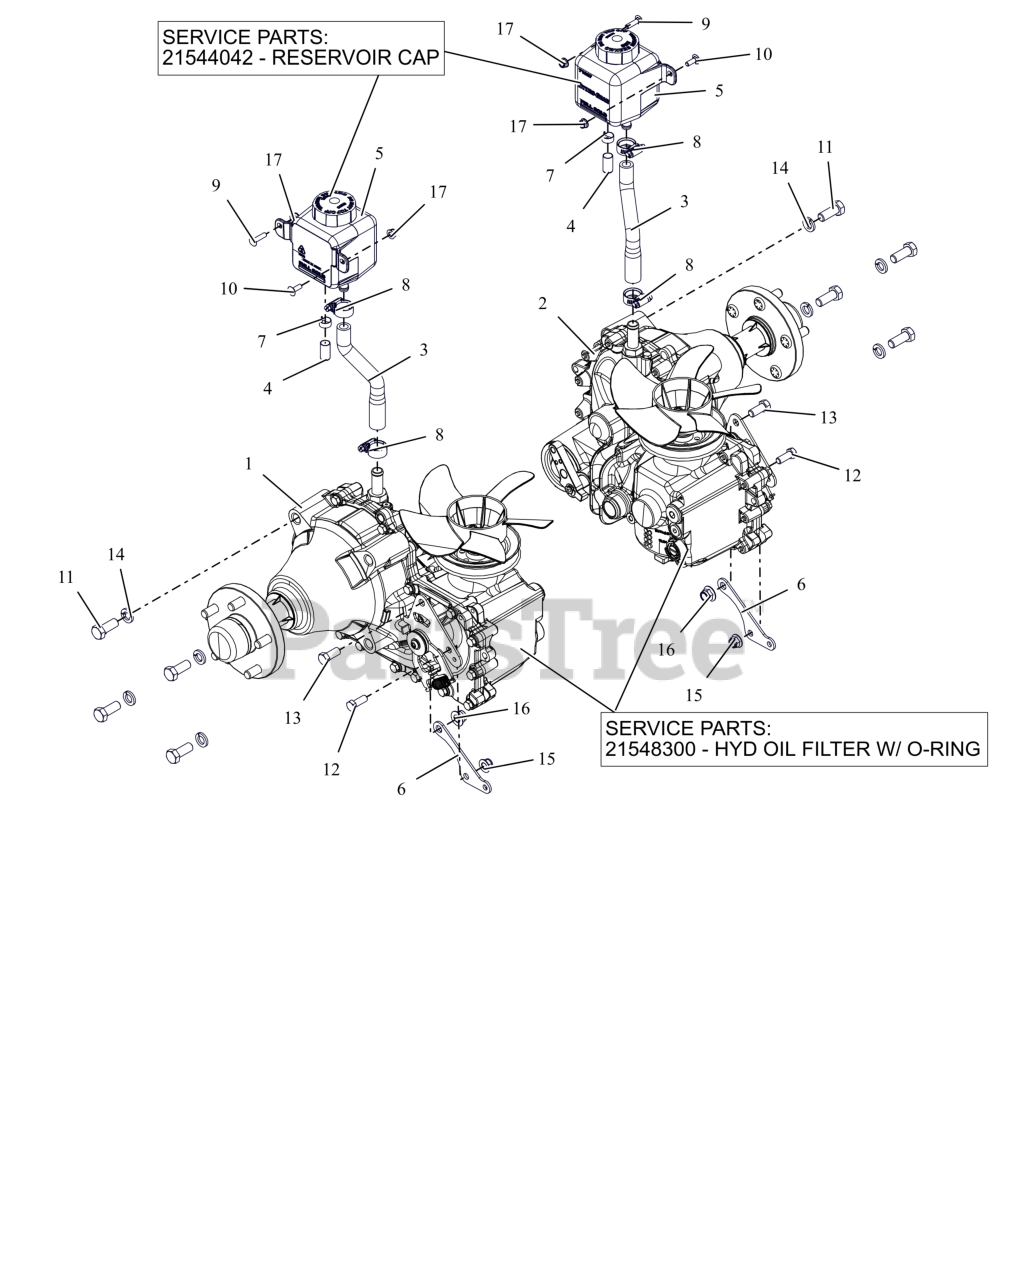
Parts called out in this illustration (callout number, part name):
1	TRANS, RH HG ZT-5400
1	FILTER,HYD OIL W/ORING ZT-54OO
2	TRANS, LH HG ZT-5400
2	FILTER,HYD OIL W/ORING ZT-54OO
3	HOSE,PT200/400 TRANS OVERFLOW
4	CAP, .50 BARBED FITTING
5	TANK, HYDRO OVERFLOW 700 ML
5	CAP, HYDRO RESERVOIR REPLAC.
6	DRV CNTRL LINKAGE MTG BRKT-BLK
7	CLAMP, .62 SPRING
8	CLAMP,.88 DIA. HOSE
9	@BLT-RDHDSQNK .25-20X1.00 G5YZ
10	@BLT-RDHDSQNK .25-20X.75 G5YZ
11	@BLT-HEX .50-13X1.25 GR5 YWZC
12	@BLT-HEX .38-16X1.00 GR5 YWZC
13	@BLT-HEX .44-14X1.00 GR5 YWZC
14	@WSHR-LK .50X.125 REG YWZC
15	@NUT-LK-NYL-FLG .38-16 YWZC
16	@NUT-LK-NYL-FLG .44-14 YWZC
17	@NUT-LK-NYL-FLG .25-20 YWZC
